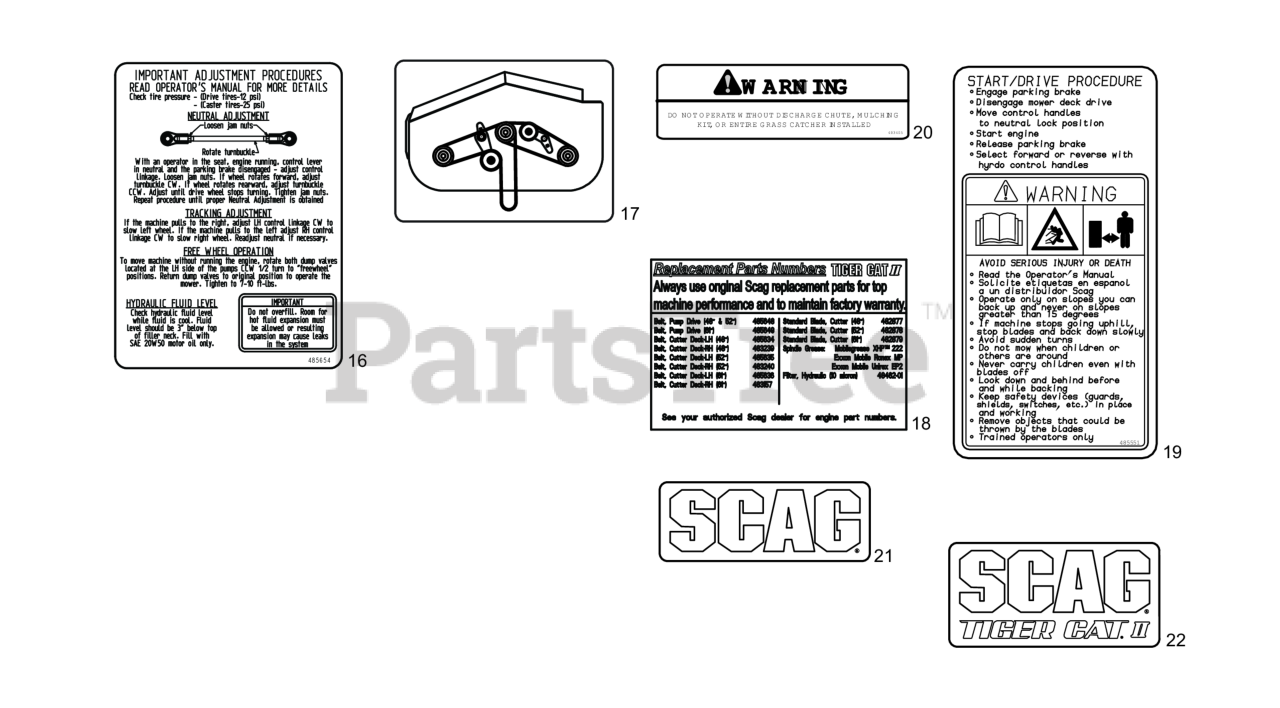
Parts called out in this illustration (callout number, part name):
16	Decal, Seat Support
17	Decal, Cutter Deck Belt Routing
18	Decal, STCII Replacement Parts
19	Decal, Start/Drive
20	Decal, Warning-Discharge
21	Decal, Scag
22	Decal, Scag Tiger Cat II
